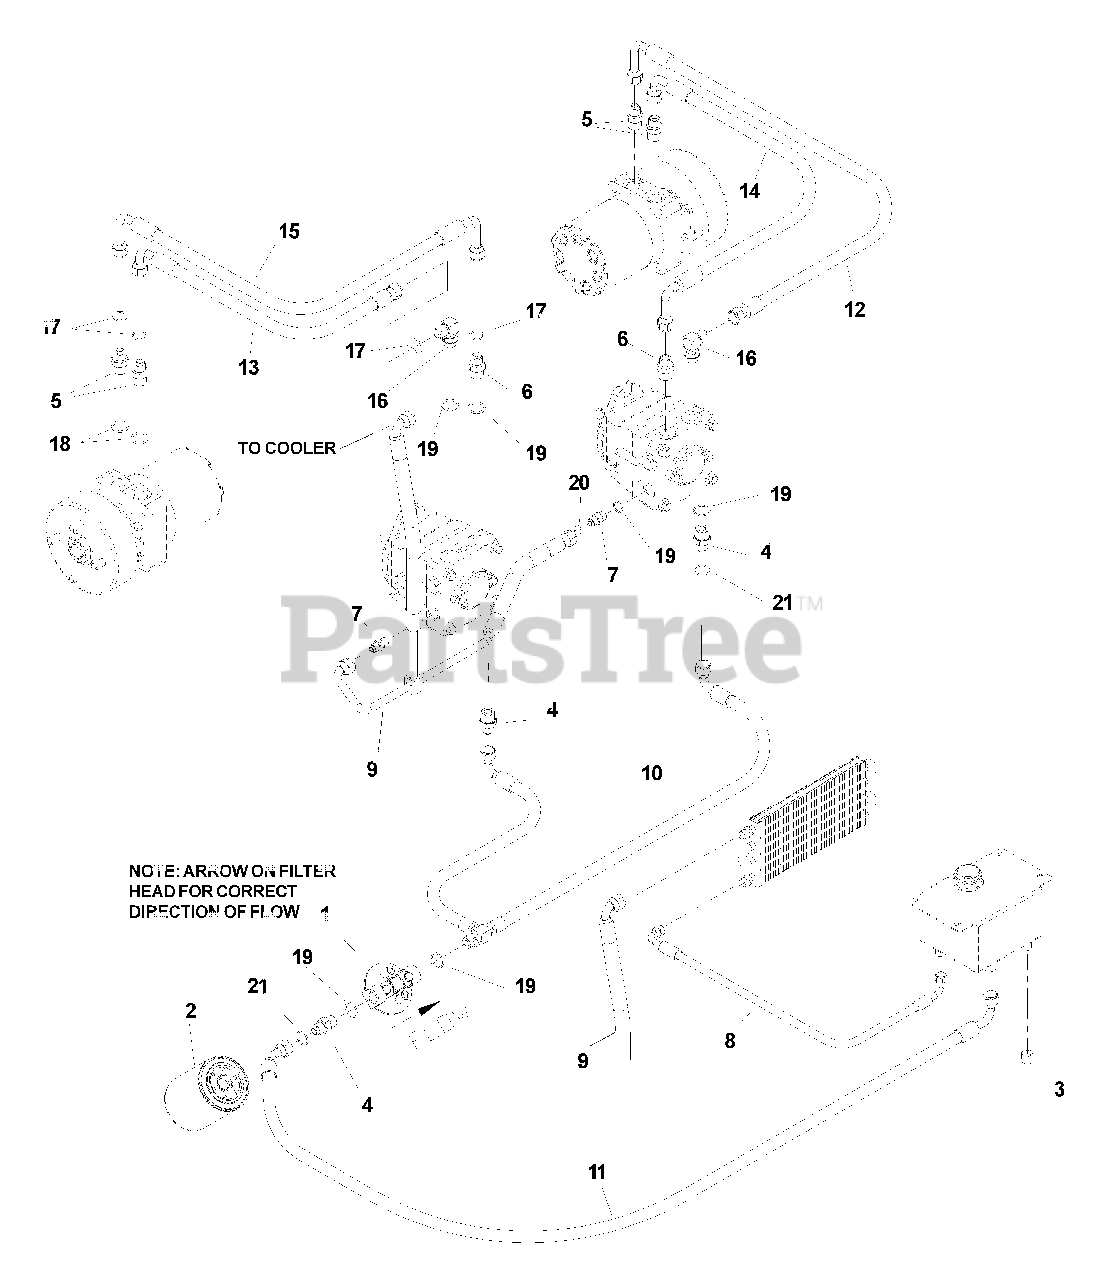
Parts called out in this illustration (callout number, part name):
1	Filter head
3	Cap nut, reservoir drain
4	Straight connector
5	Fitting, wheel motors
6	Fitting, pumps
7	Fitting, pumps (return side)
8	Hose, cooler-reservoir
9	Hose, T, pumps-cooler
10	Hose, T, filter, out-pumps
11	Hose, reservior-filter, in
12	Hose, LL pump-LR mtr
13	Hose, RR pump-RF mtr
14	Hose, LR pump-LF mtr
15	Hose, RL pump-RR mtr
19	O-Ring, SAE J126 Port
